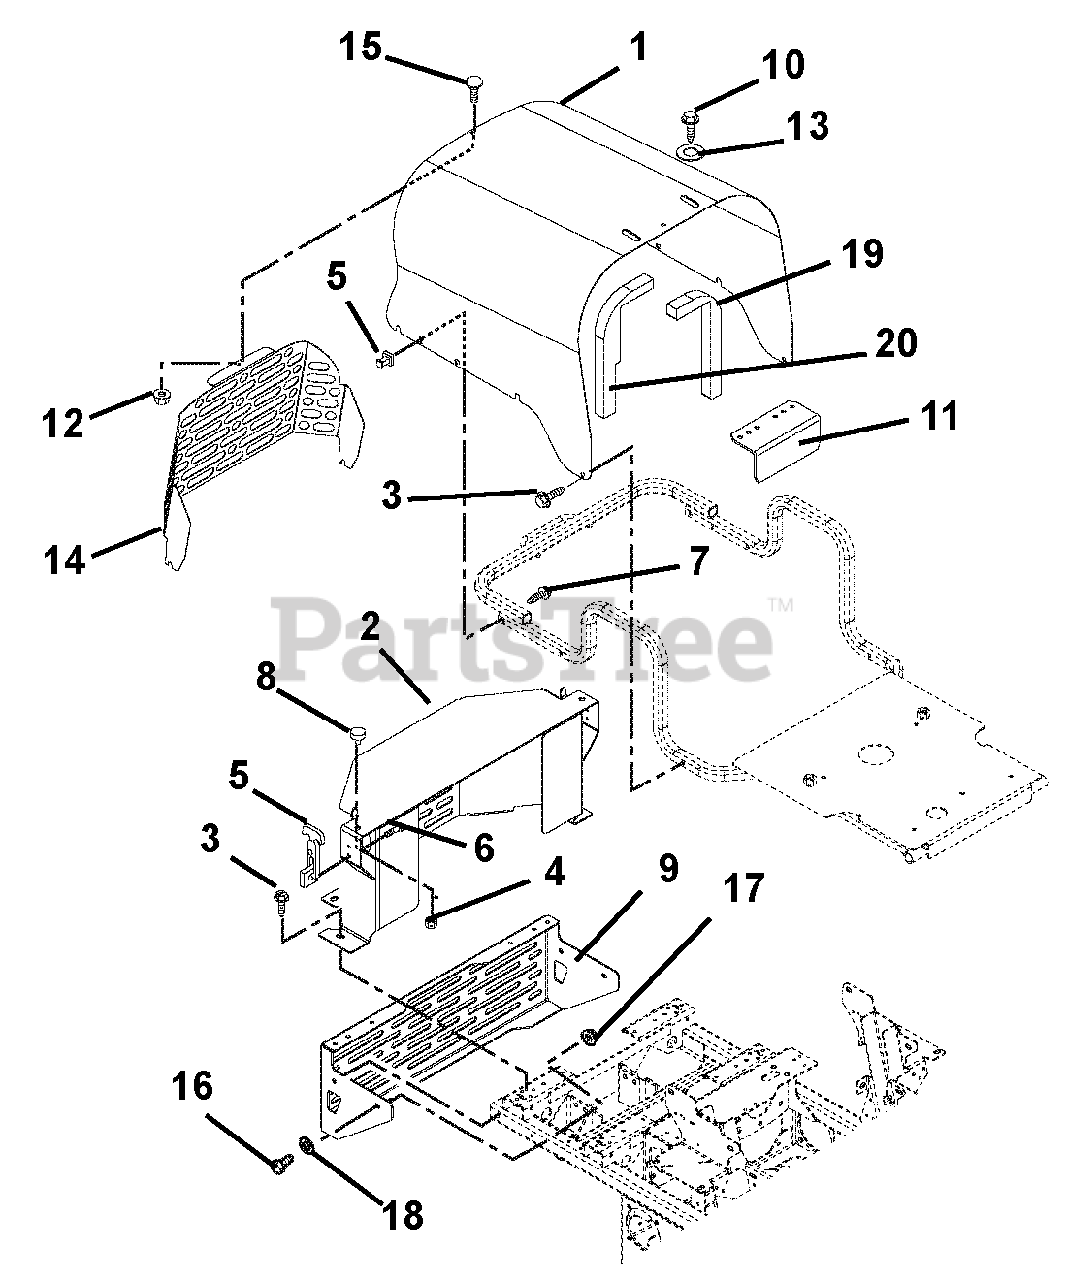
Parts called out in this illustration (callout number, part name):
1	HOOD-L/C - RED
2	WMT-DIESEL BELT GUARD
3	@SCR-TAP .38-16X.75 HWH TR YWZ
4	@NUT-SPNLK-FLG .312-18 YWZC
5	LATCH, RUBBER
6	@SCR-MCH 10-24X.50 HWH YWZC
7	@SCR-MCH 10-24X1.50 HWH YWZC
8	BUMPER, RUBBER
9	WMT-BUMPER-PM200
10	@SCR-TAP .25-20X.50 HWH TR YWZ
11	GUARD, RADIATOR CAP- DIESEL
12	@NUT-LK-TOP-FLG .25-20 YWZC
13	@WSHR-FL-STL.281X.62X.065 YWZC
14	GUARD-L/C HOOD - BLACK
15	@BLT-RDHDSQNK .25-20X.50 G5YZ
16	@BLT-HEX .38-16X2.75 GR5 YWZC
17	@NUT-LK-TOP-FLG .38-16 YWZC
18	@WSHR-FL-STL.406X.812X.065 YWZ
19	DAM, LEFT SIDE FOAM AIR
20	DAM, RIGHT SIDE FOAM AIR
